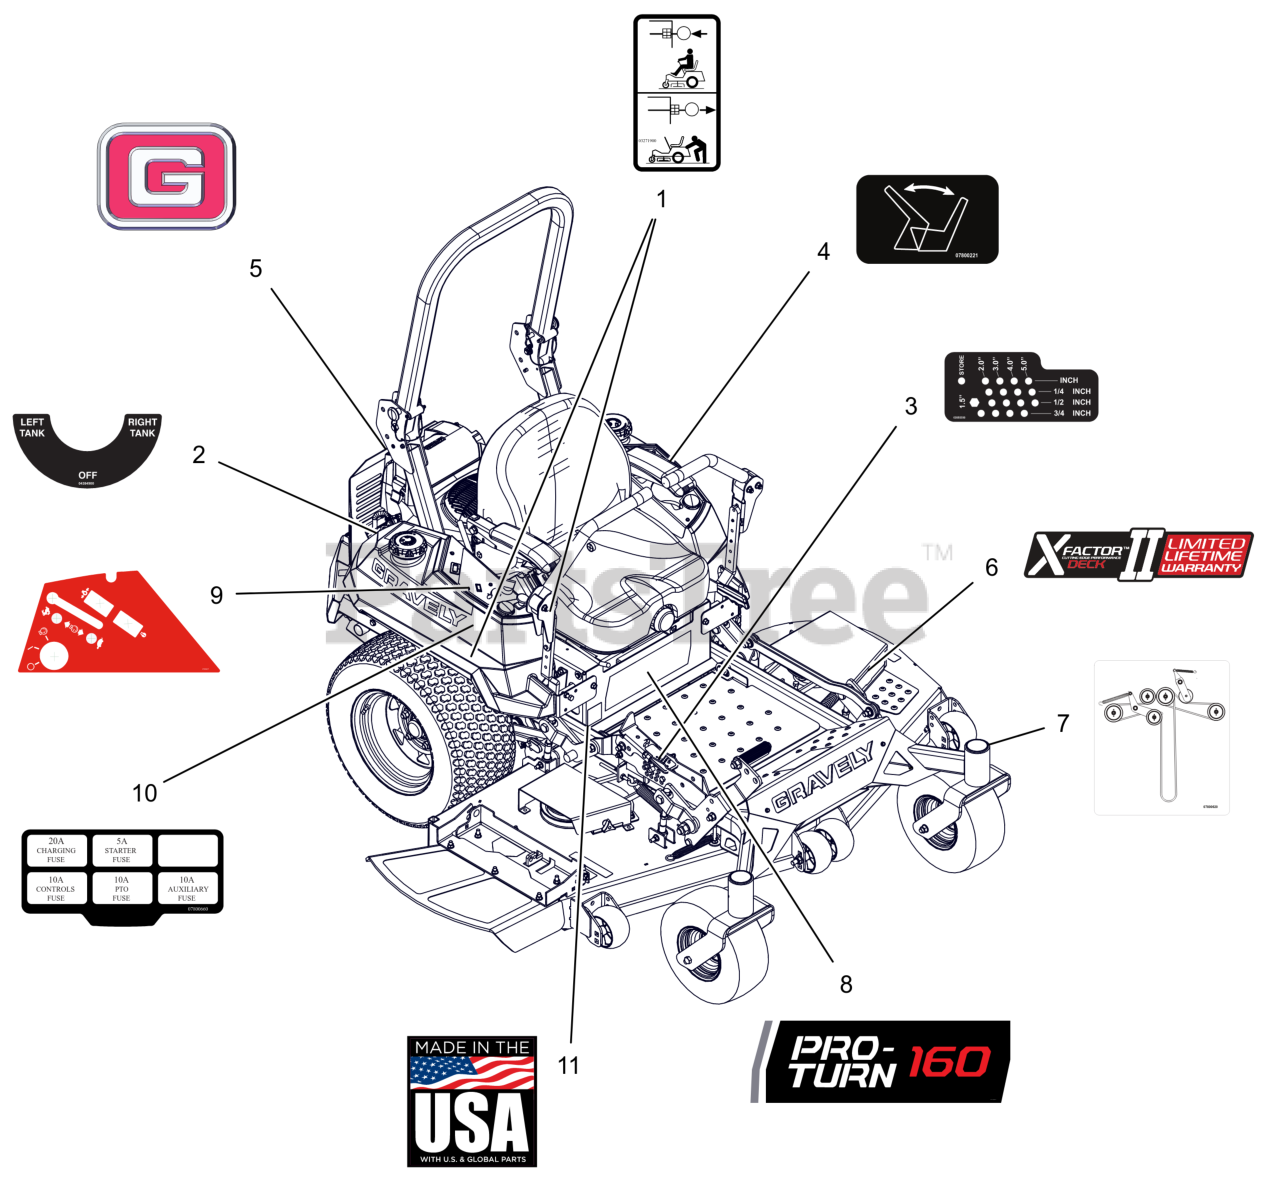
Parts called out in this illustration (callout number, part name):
1	DECAL, TRANSMISSION DISCONNECT
2	DECAL, FUEL VALVE
3	DECAL, HEIGHT OF CUT
4	DECAL - SEAT RELEASE
5	DECAL, GRAVELY BRAND
6	DECAL, X-FACTOR DECK
7	DCL,BELT ROUTE-RH BK-SIDE IDLR
8	DECAL, PRO-TURN 160
9	DECAL, EFI CONTROL PANEL
10	DECAL, FUSE BLOCK
11	DECAL, MADE IN USA
